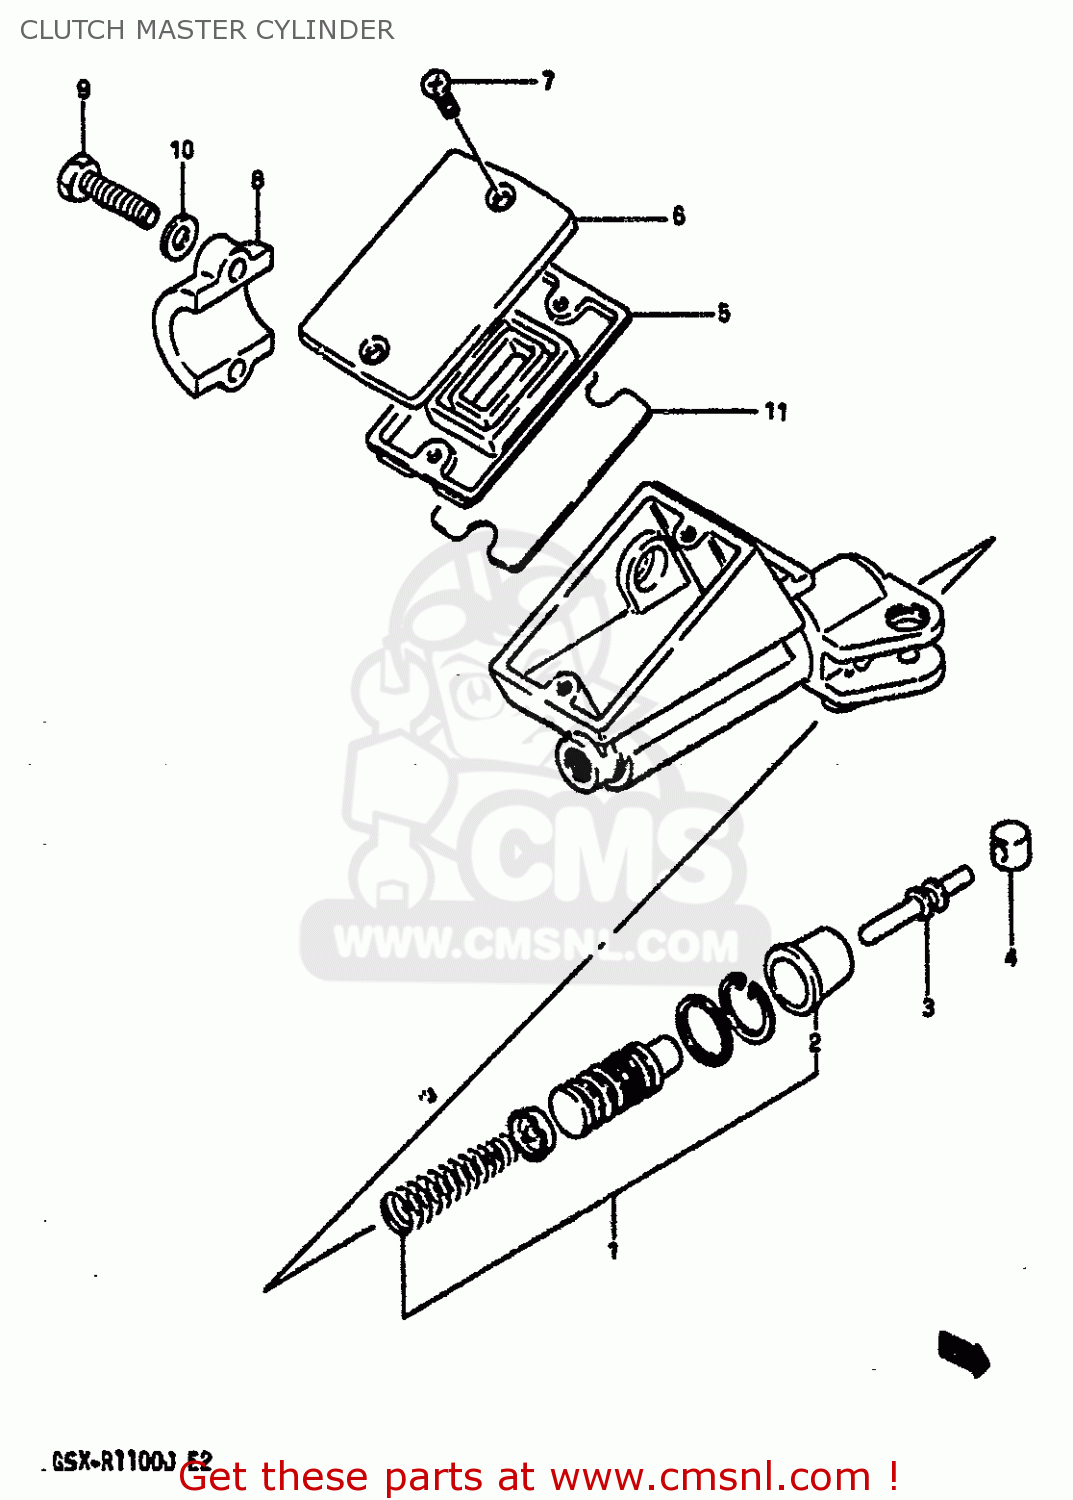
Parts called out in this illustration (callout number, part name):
1	PISTON & CUP SET
2	BOOT
3	ROD,PUSH
4	BUSH
5	6
6	CAP
7	SCREW
8	HOLDER,MASTER CYLINDER
9	BOLT
10	WASHER
11	FLOAT
